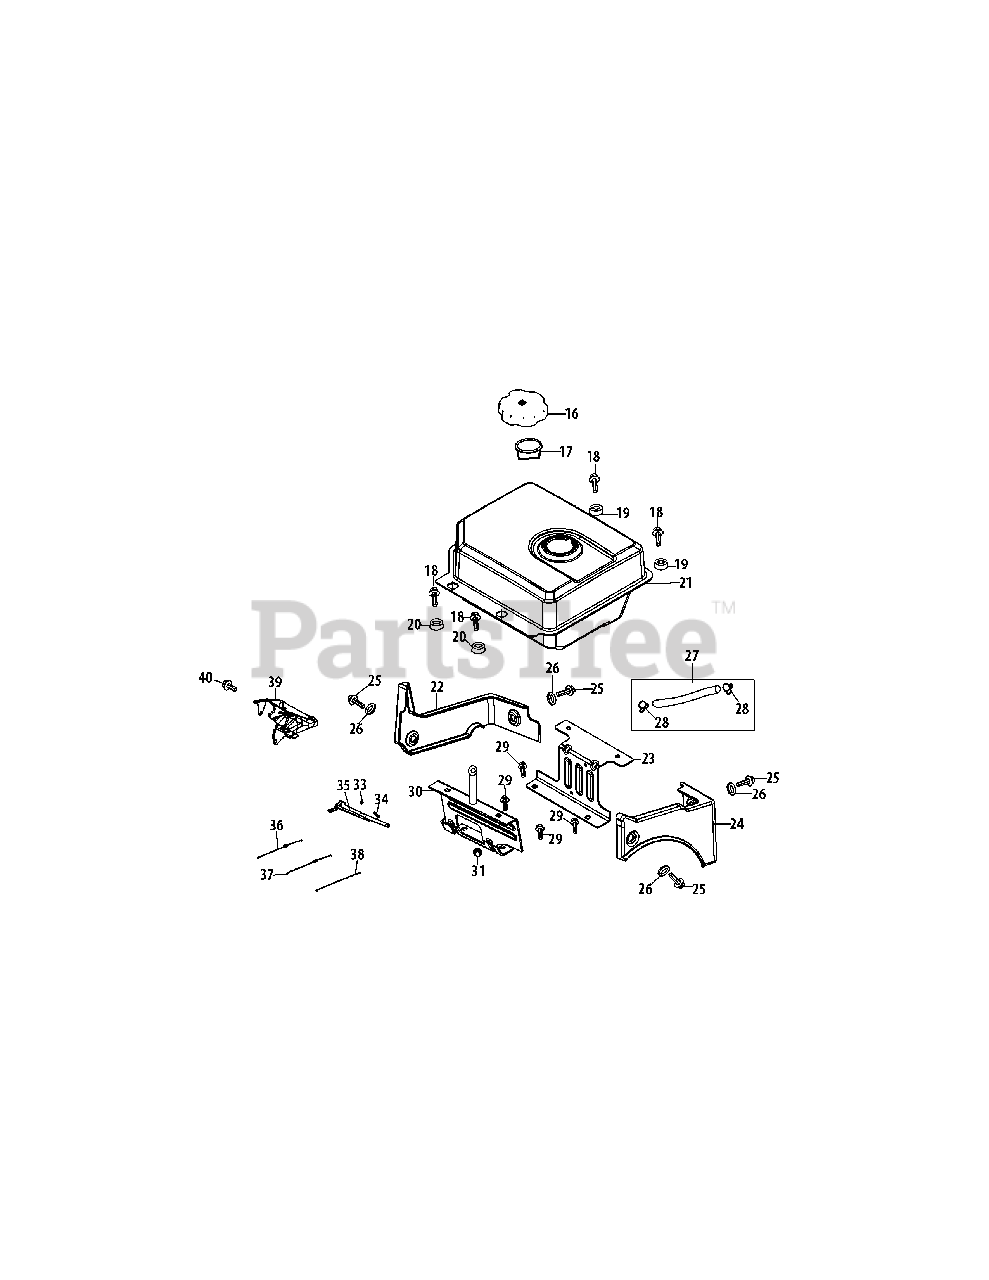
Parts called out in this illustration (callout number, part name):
16	Fuel Cap Assembly Viton / Vented
17	Fuel Level Indicator
18	Bolt M8×20
19	Bush, Gas Tank
20	Bush,Gas Tank
21	Fuel Tank Assembly
22	Fuel Tank Shroud
23	Fuel Tank Mounting Bracket
24	Engine Shroud
25	Bolt M6×16
27	Fue Line Kit
28	Fuel Hose Clamp
29	Bolt M8×14
30	Fuel Tank Mounting Bracket
33	Nut M6
34	Governor Arm Bolt
35	Governor Arm
36	Governor Spring
37	Throttle Linkage Spring
38	Throttle Linkage
39	Primer Bracket
40	Bolt M6×14
